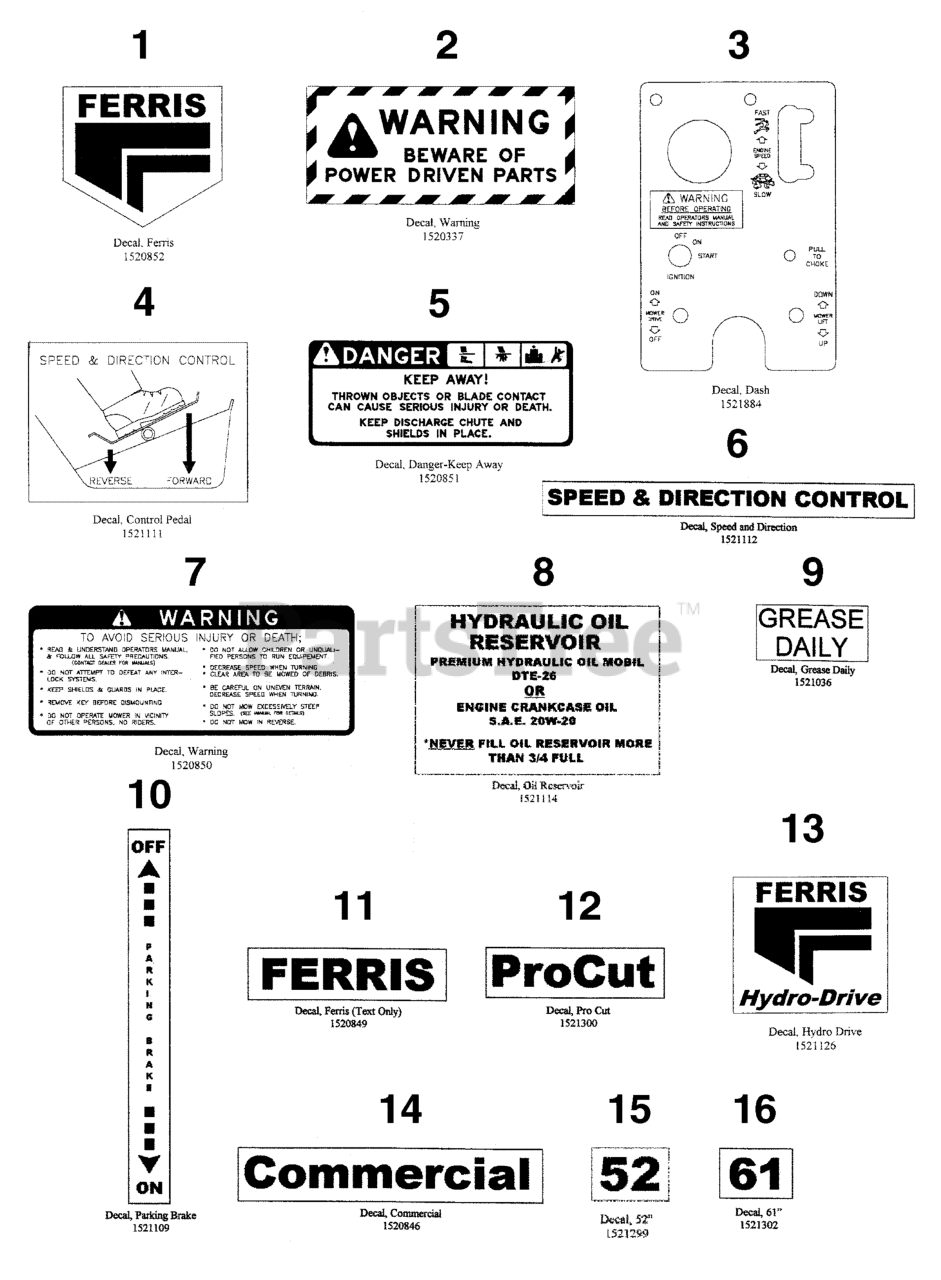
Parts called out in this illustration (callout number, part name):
1	DECAL, Ferris Logo, 10-3/4"
2	DECAL, Warning
3	DECAL, Dash
4	DECAL, Speed Control
5	DECAL, DANGER DO NOT OPERATE W/O DEFLECT
7	DECAL, WARNING Operation
8	DECAL, Reservior Hydraulic Oil
9	DECAL, Grease Daily
10	DECAL, PARKING BRAKE-RIDER
11	DECAL, FERRIS TEXT & LOGO
12	DECAL, ProCut
13	DECAL, Hydro Drive
14	DECAL, Commerical
15	DECAL, 52
16	DECAL, 61"
